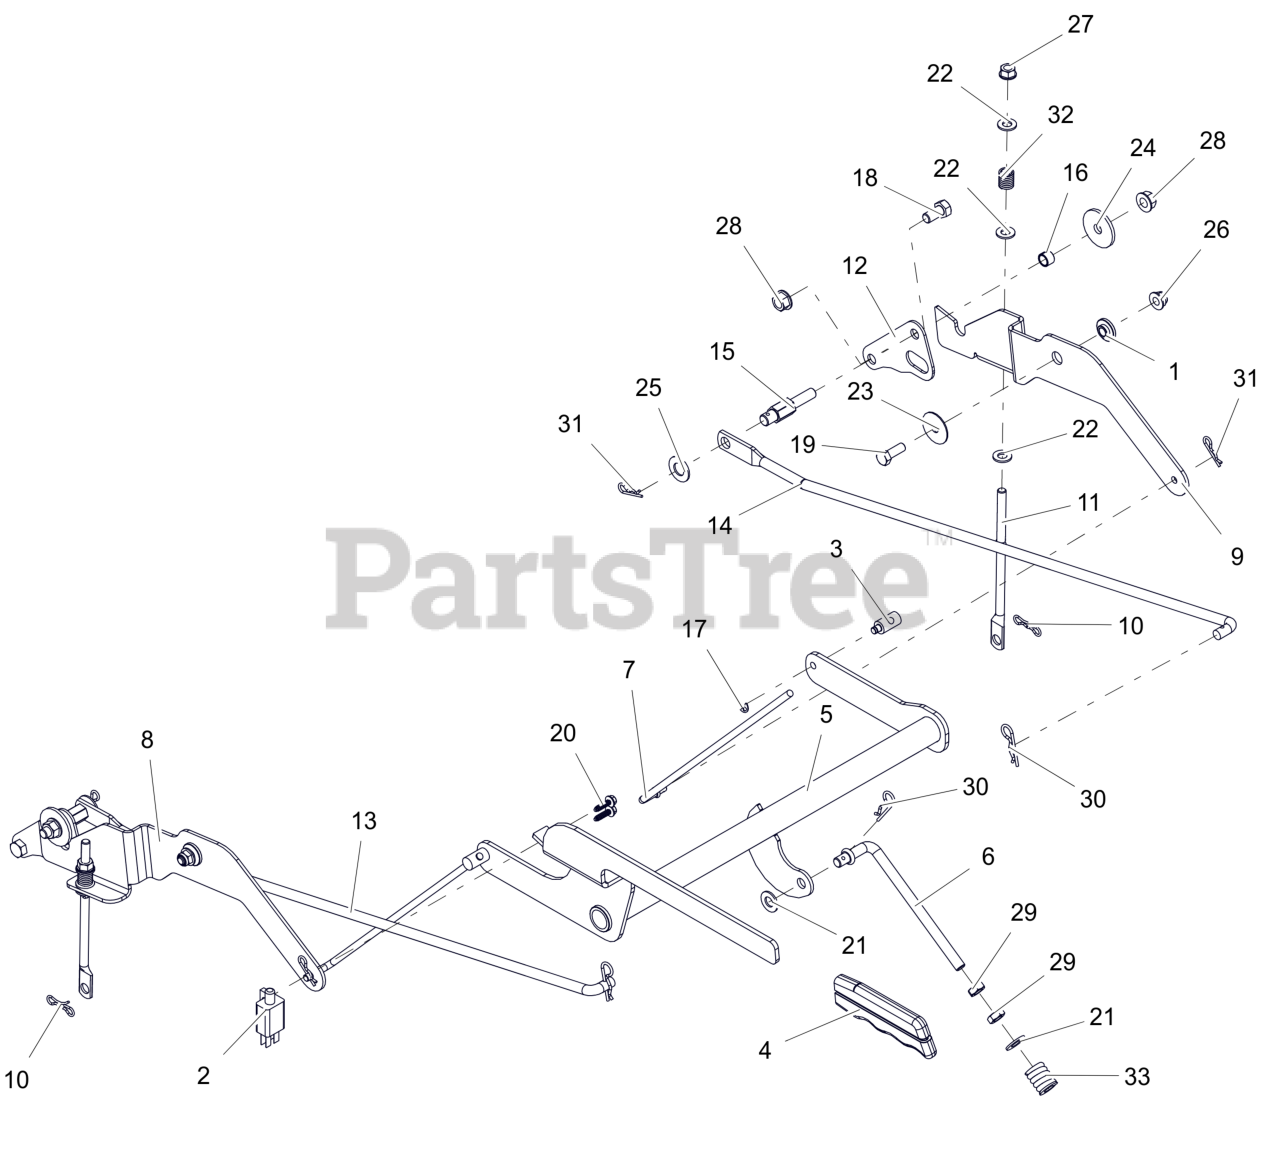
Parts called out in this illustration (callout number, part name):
1	BSHG, FLG .325X.499X.26X.88
2	SWITCH- DOUBLE POLE N.O./N.O.
3	TRUNION, 1/4-20
4	GRIP, PARKING
5	WLDMT, BRAKE LEVER
6	LINK, OVER CENTER, PARKING BRK
7	ROD, PARK BRAKE
8	INTERLOCK- RH BRAKE LINK
9	INTERLOCK- LH BRAKE LINK
10	PIN, BOWTIE #72 ZCC
11	LINK, TRANSAXLE BRAKE
12	PLATE, TRANSAXLE ADAPTOR
13	LINKAGE, STEERING - RH
14	ROD, STEERING LINKAGE LH
15	POST, STEERING LINK MOUNTING
16	SPCR, SLV .385X.500X.350
17	RG-RTNG-EXT .250X.025
18	BLT,HEX .38-16X.75 G5 ZCC
19	BLT, HEX .31-18X.875 G5 ZCC
20	SCR, PLASTITE-HWH 0.2 X 0.75 ZC120
21	WSHR,FLT .406X.812X.065 ZCC
22	WSHR,FLT .344X.688X.065 ZCC
23	WSHR, FLT .347X1.254X.048 ZCC
24	WSHR, FLT .380X1.50X.125 ZCC
25	WSHR, FLT .505X1.00X.062 ZCC
26	NUT,NYL-FLG .31-18 GF ZCC
27	NUT,LK-CTR-FLG .31-18 GF ZCC
28	NUT-LK-CTR-FLG .375-16 GF ZCC
29	NUT-JAM .375-16 G2 ZCC
30	PIN, HAIR .09 X 1.50 ZCC
31	PIN, HAIR #213 .08X1.19 ZCC
32	SPRING, COMPRESSION
33	SG-COMP .187X.56X1.62
